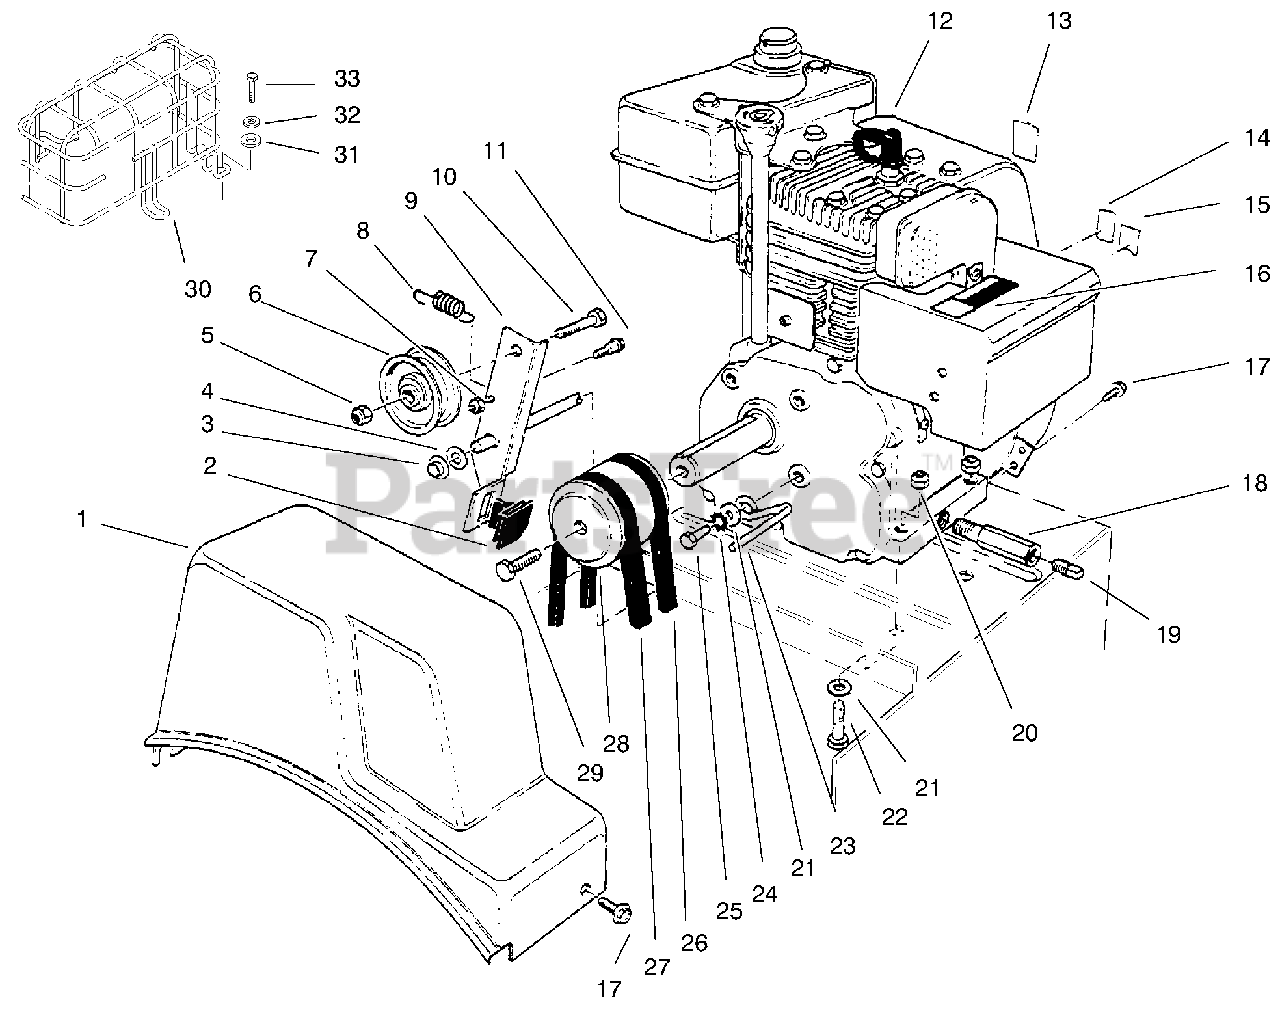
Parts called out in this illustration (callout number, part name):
1	COVER - BELT
2	PAD-BRAKE
3	NUT-LOCK, NI
4	WASHER-FLAT
5	RETAINER-PUSH ON
6	PULLEY-IDLER
7	NUT-LOCK, NI
9	Auger Clutch (Incl. Ref. #2)
10	SCREW-HH
11	BOLT-SHOULDER
12	Engine
13	DECAL - PRIMER
14	THROTTLE DECAL, INT'L
15	CHOKE DECAL
16	DECAL-WARNING, HOT SURFACE
17	SCREW-HWH
18	PIPE-NIPPLE
19	CAP-PIPE
20	NUT-LOCK, NI
21	WASHER-FLAT
22	SCREW-HH
23	RETAINER-BELT
24	WASHER-LOCK/EXT
25	SCREW-HH
28	PULLEY-ENGINE
29	SCREW-SPECIAL
30	Guard-Muffler Model 38054
31	Washer-Flat
32	Washer-Lock
33	Screw
